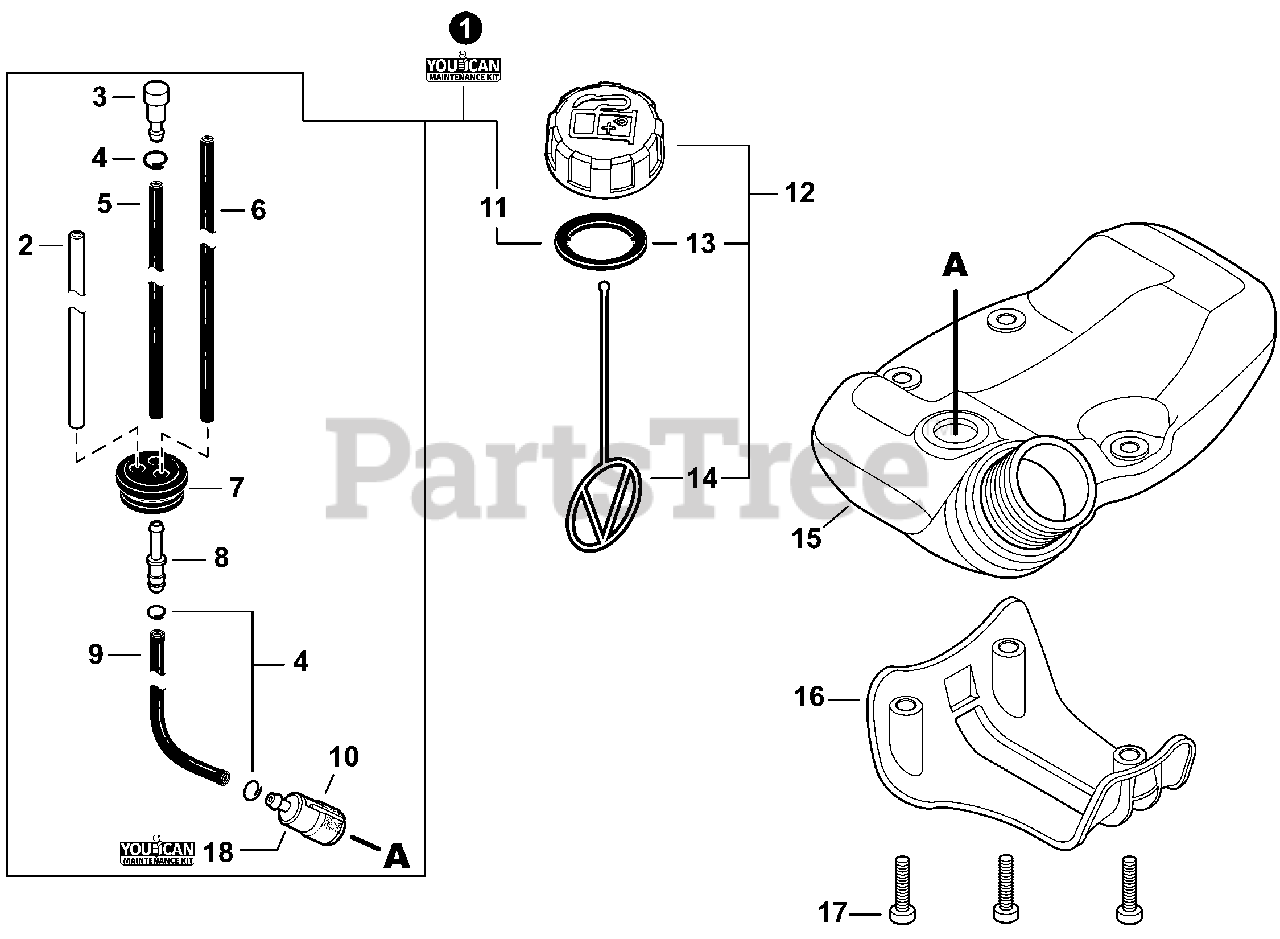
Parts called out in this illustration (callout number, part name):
1	FUEL SYSTEM KIT - YOUCANT
2	PIPE, FUEL 3×6×80 CLEAR
3	VENT ASSY
4	CLIP Ø6
5	PIPE, FUEL 3×5×90 BLACK
6	PIPE, FUEL 3×5×74 BLACK
7	GROMMET, FUEL Ø5
8	CONNECTOR, PIPE Ø5ר3.5
9	PIPE, FUEL 3×5×130 BLACK
10	FILTER, FUEL
11	GASKET, FUEL CAP
12	CAP ASSY, FUEL
13	GASKET, FUEL CAP
14	CONNECTOR, CAP L= 123
15	TANK ASSY, FUEL
16	GUARD, FUEL TANK
17	BOLT, TORX 5×20
18	TUNE-UP KIT - YOUCANT
